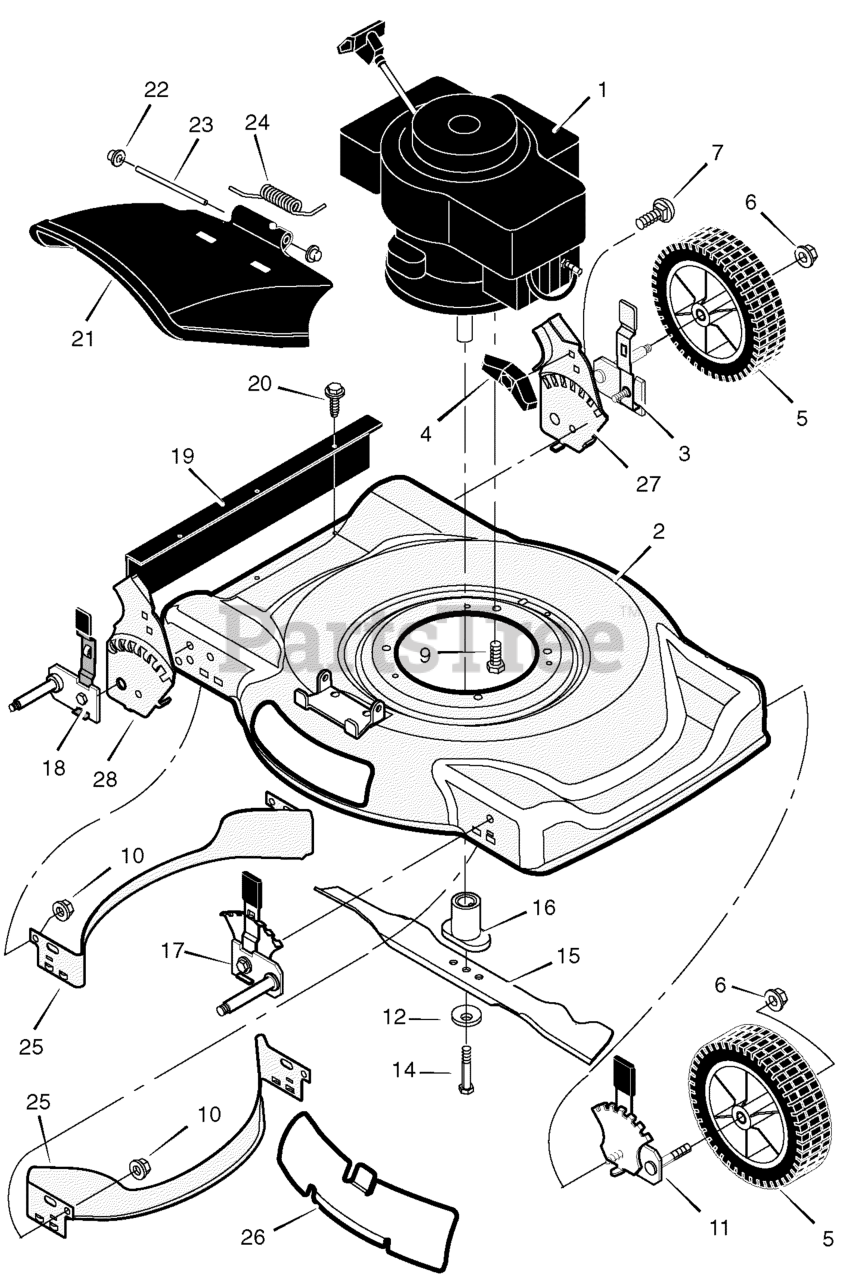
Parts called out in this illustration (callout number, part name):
1	Engine*
2	Housing
3	Height Adjuster, Left Rear (8" Wheels)
5	Wheel and Tire
6	Locknut, Flange
7	Bolt, Carriage
9	Bolt, Engine
10	Nut
11	Height Adjuster, Left Front (8" Wheels)
12	Washer, Belleville
14	Bolt, Hex
16	Adapter, Blade
17	Height Adjuster, Right Front (8" Wheels)
18	Height Adjuster, Right Rear (8" Wheels)
19	Guard, Rear
21	Deflector, Chute
22	Push-On Cap
23	Pin, Pivot
24	Spring
25	Baffle Optional Accessory
26	Plate, Mulcher
27	Bracket, Left Handle
28	Bracket, Right Handle
